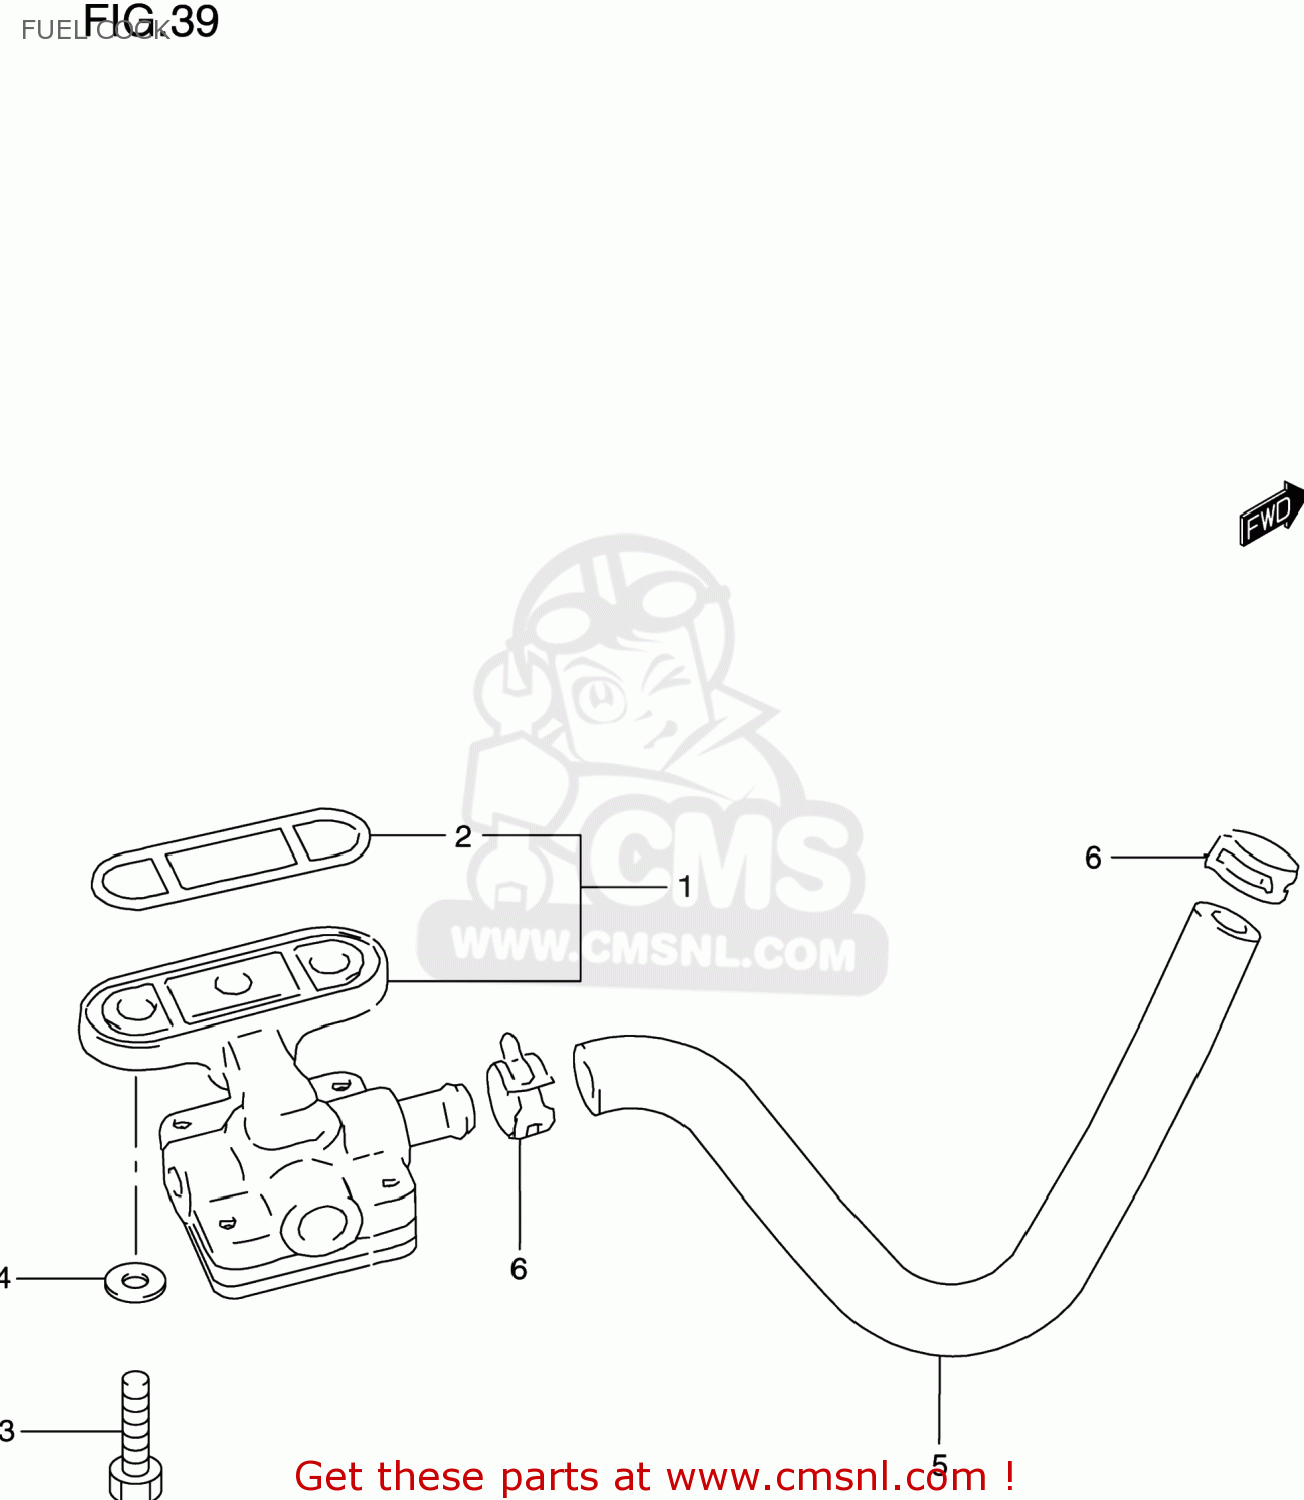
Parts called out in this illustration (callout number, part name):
1	COCK ASSEMBLY,FUEL
2	O RING,JOINT
3	BOLT(6X20)
4	GASKET(6.4X11.5X0.8) (NAS)
5	HOSE(7X12X600)
6	CLIP
